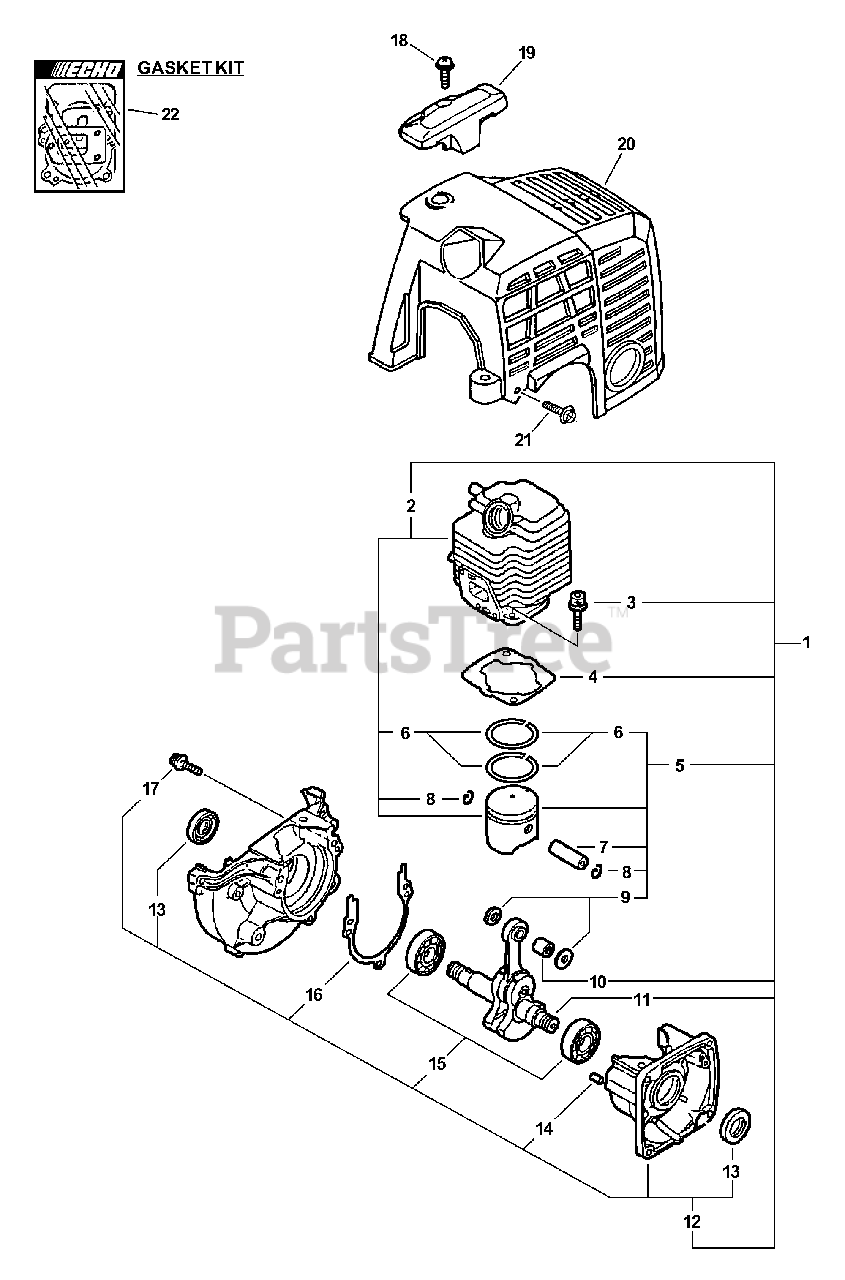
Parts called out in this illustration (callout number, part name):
1	SHORT BLOCK -- SB1027
2	CYLINDER KIT
3	SCREW - 5X22
4	GASKET, CYLINDER
5	PISTON KIT
6	RING, PISTON
7	PIN, PISTON
8	RING, RETAINING
9	SPACER, PISTON
10	BEARING, NEEDLE
11	CRANKSHAFT ASSY
12	CRANKCASE KIT
13	SEAL, OIL
14	PIN - LOCATING
15	BEARING, BALL - 6201
16	GASKET, CRANKCASE
17	SCREW - 5X28
18	SCREW - 5X16
19	GUARD - TOP
20	COVER, ENGINE
21	SCREW - 4X16
22	GASKET KIT
